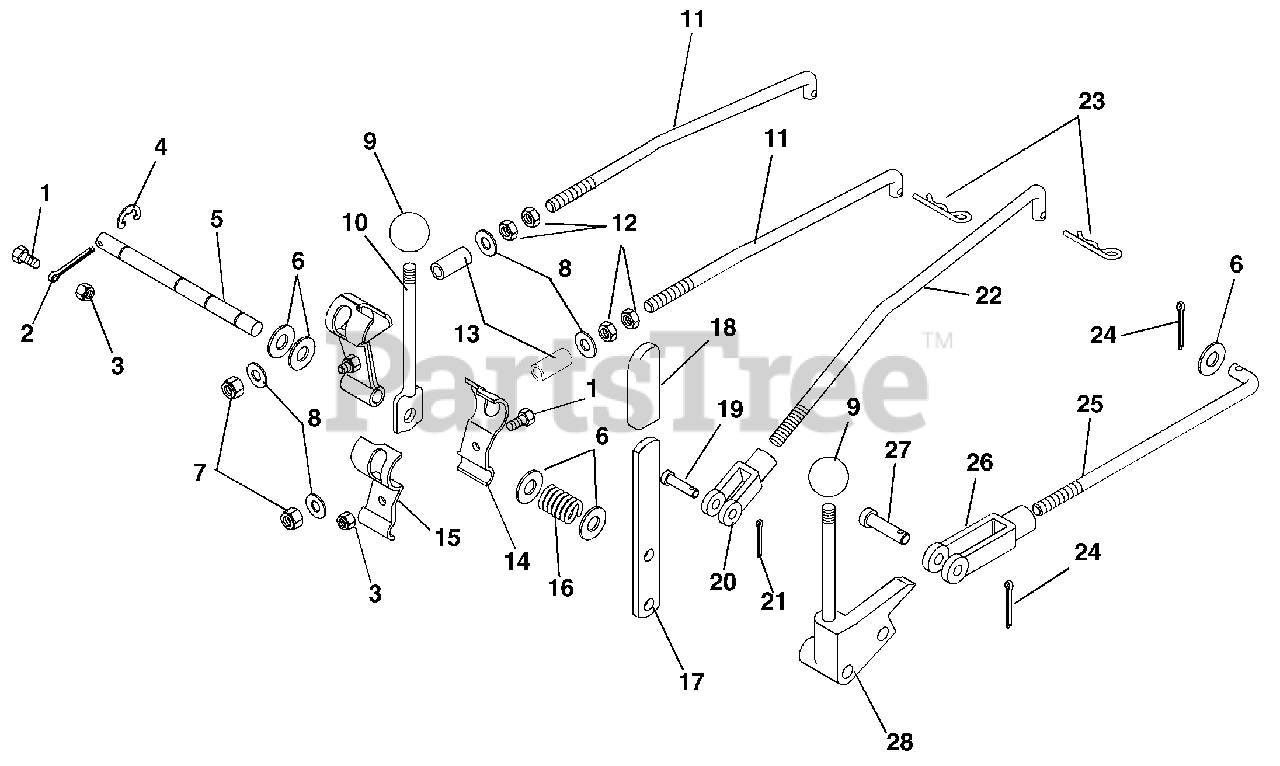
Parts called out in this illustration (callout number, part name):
1	Bolt-Hex .31-18 x .75 Grade 5
2	Pin-Cotter .25 x 2.00
3	Nut-Locking-Center .31-18
4	Ring-Retaining-External .50 x .042
5	Shaft, Cross
6	Washer-Flat-Steel .53 x 1.06 x .095
7	Nut-Locking-Center .38-16
8	Washer-Flat-Steel .44 x 1.00 x .083
9	Knob-Control .44-20 x .50
10	Lever, Shift
11	Rod, Shift
12	Nut-Hex-Jam .38-16
13	Bushing-Sleeve .40 x .49 x 1.63 Steel
14	Arm, Shifter Right
15	Arm, Shifter Left
16	Spring-Compression .085 x .50 x 2.75
17	Lever, High-Low Shift
18	Grip, Handle
19	Pin-Clevis .38 x .95
20	Clevis,.38-24 Adjustable
21	Pin-Cotter .12 x .75
22	Rod, 2-Speed
23	Pin-Hair Internal .08 x .18 x 1.18
24	Pin-Cotter .12 x 1.00
25	Rod, PTO
26	Yoke, .50-20 x 3.00
27	Pin-Clevis .50 x 1.21
28	Assembly, PTO Control
